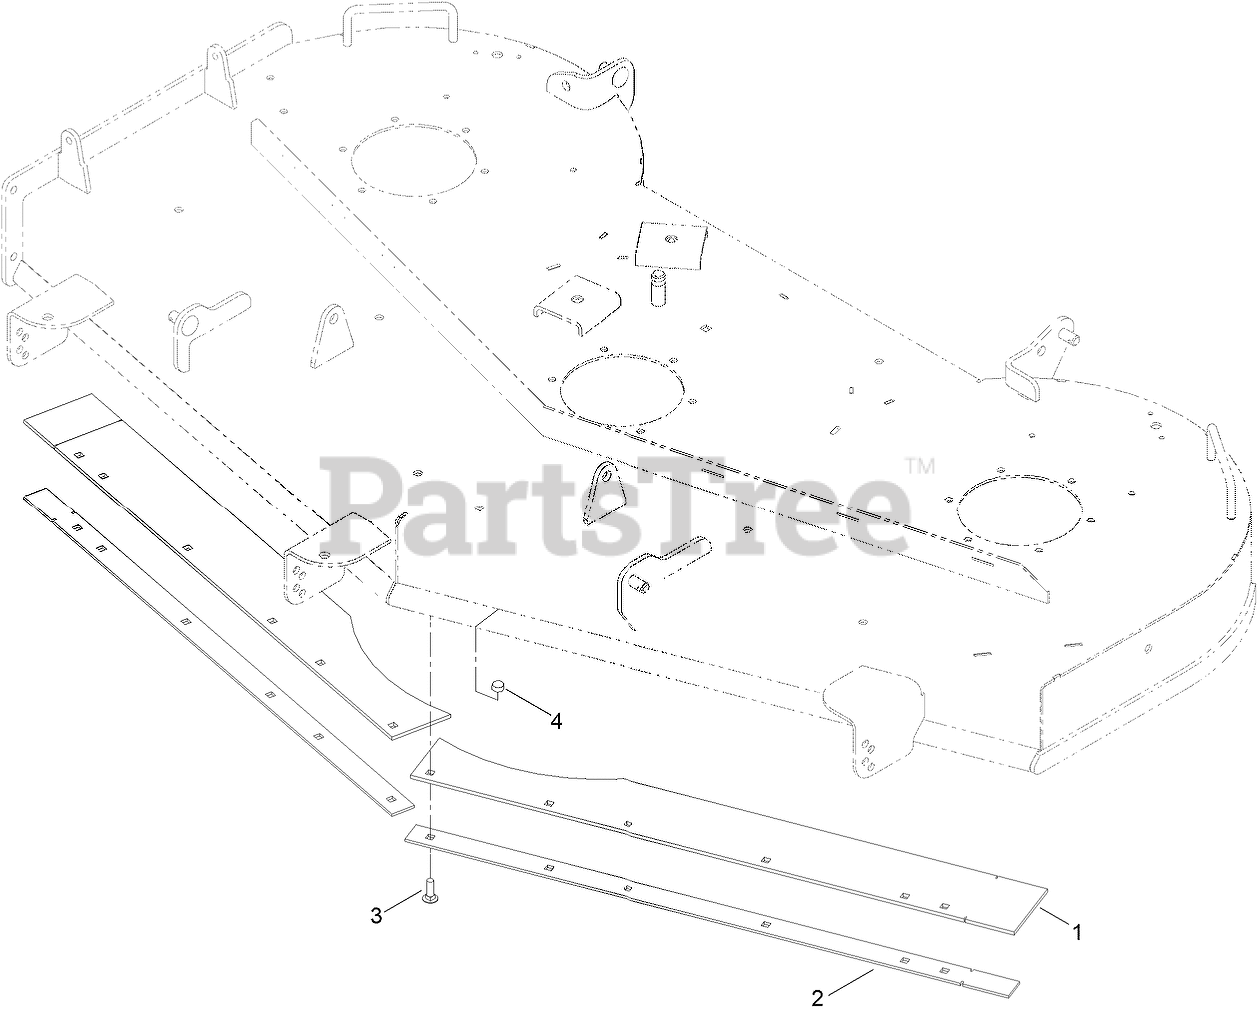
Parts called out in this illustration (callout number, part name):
1	SKIRT-RUBBER, FRONT
2	SKID-SKIRT
3	BOLT-CARR
4	NUT-HEX
